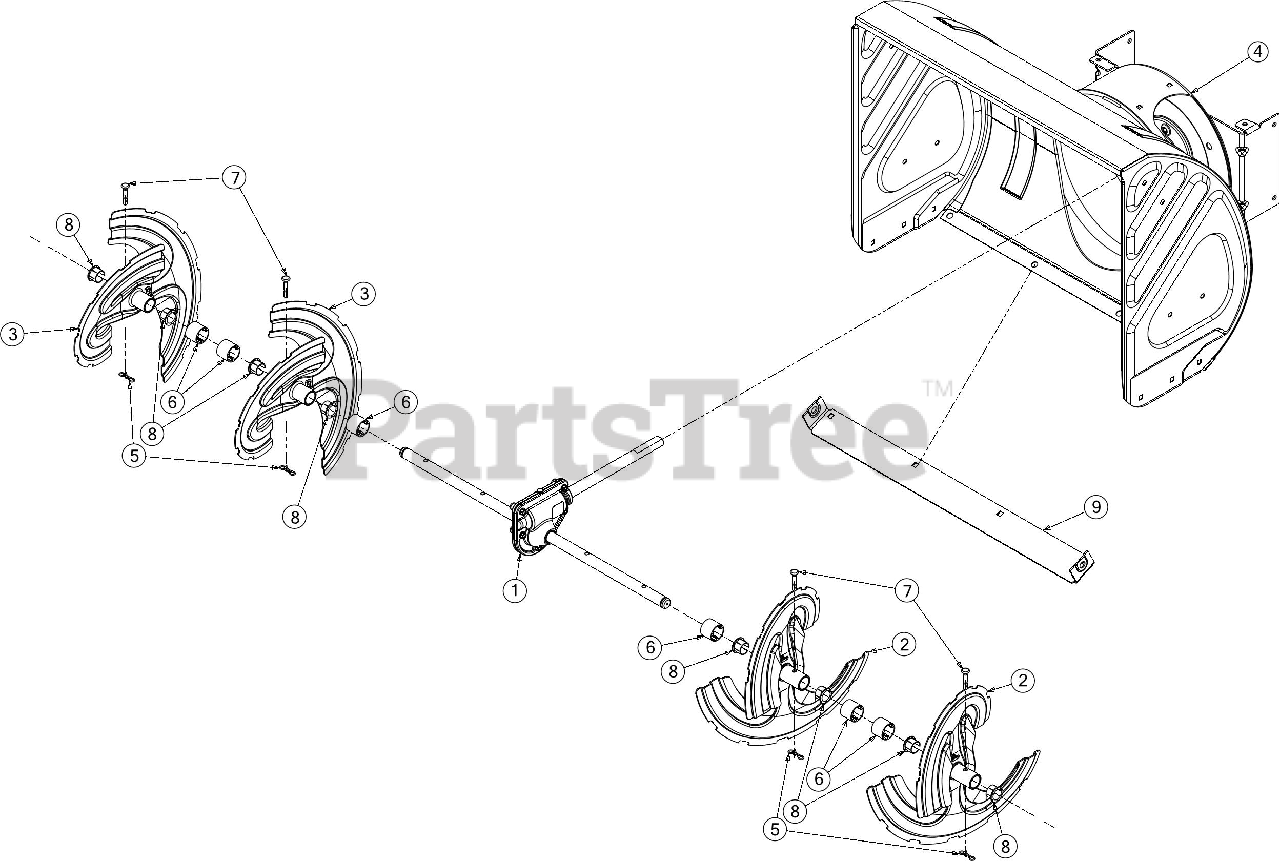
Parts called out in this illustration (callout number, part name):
1	26" GEARBOX ASSEMBLY
2	AUGER ASSEMBLY (LH)
3	AUGER ASSEMBLY (RH)
4	26" AUGER HOUSING
5	BOW TIE COTTER PIN 1/4-5/16
6	SPACER 1.25OD x .75ID X1.00 LG
7	SHEAR PIN .25 x 1.50 GR2
8	FLANGE BUSHING
9	26" SHAVE PLATE
